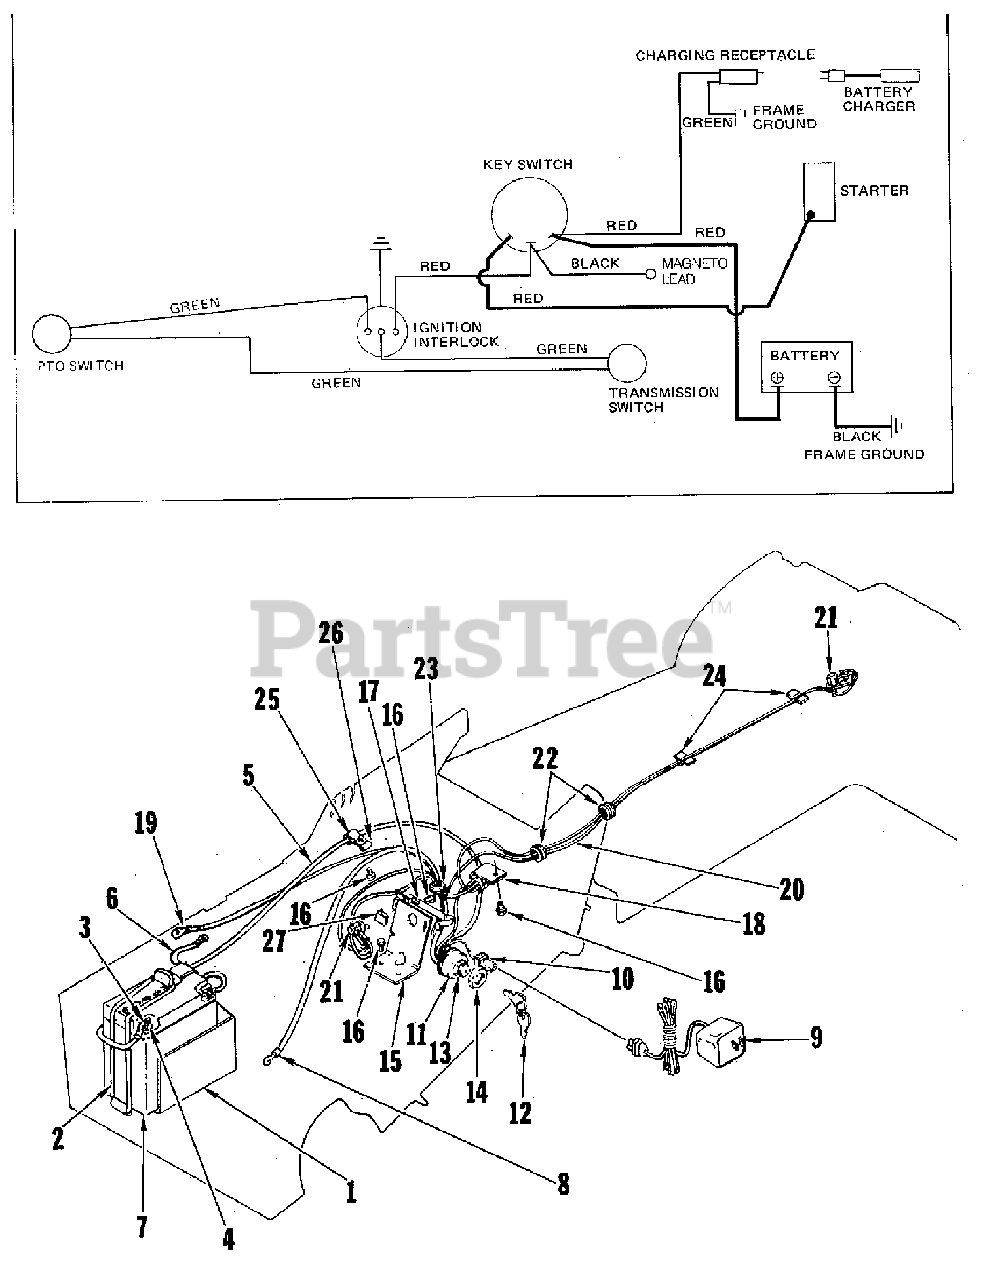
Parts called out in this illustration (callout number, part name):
1	BATTERY SUPPORT ASSEMBLY
2	STRAP, Rubber
4	SCREW, Self Tapping, 10 x 1/2
5	CABLE ASSEMBLY
6	CABLE ASSEMBLY
7	BATTERY & CLIP ASSEMBLY
8	CABLE ASSEMBLY
9	CHARGER, Battery
10	RECEPTACLE, Charger
11	IGNITION, Switch
13	WASHER, Lock, 5/8
14	NUT, Special Hex, 5/8
15	SUPPORT, Switch
16	SCREW, 1/4-20 x 3/8
17	CLIP, Spring
18	IGNITION, Interlock
